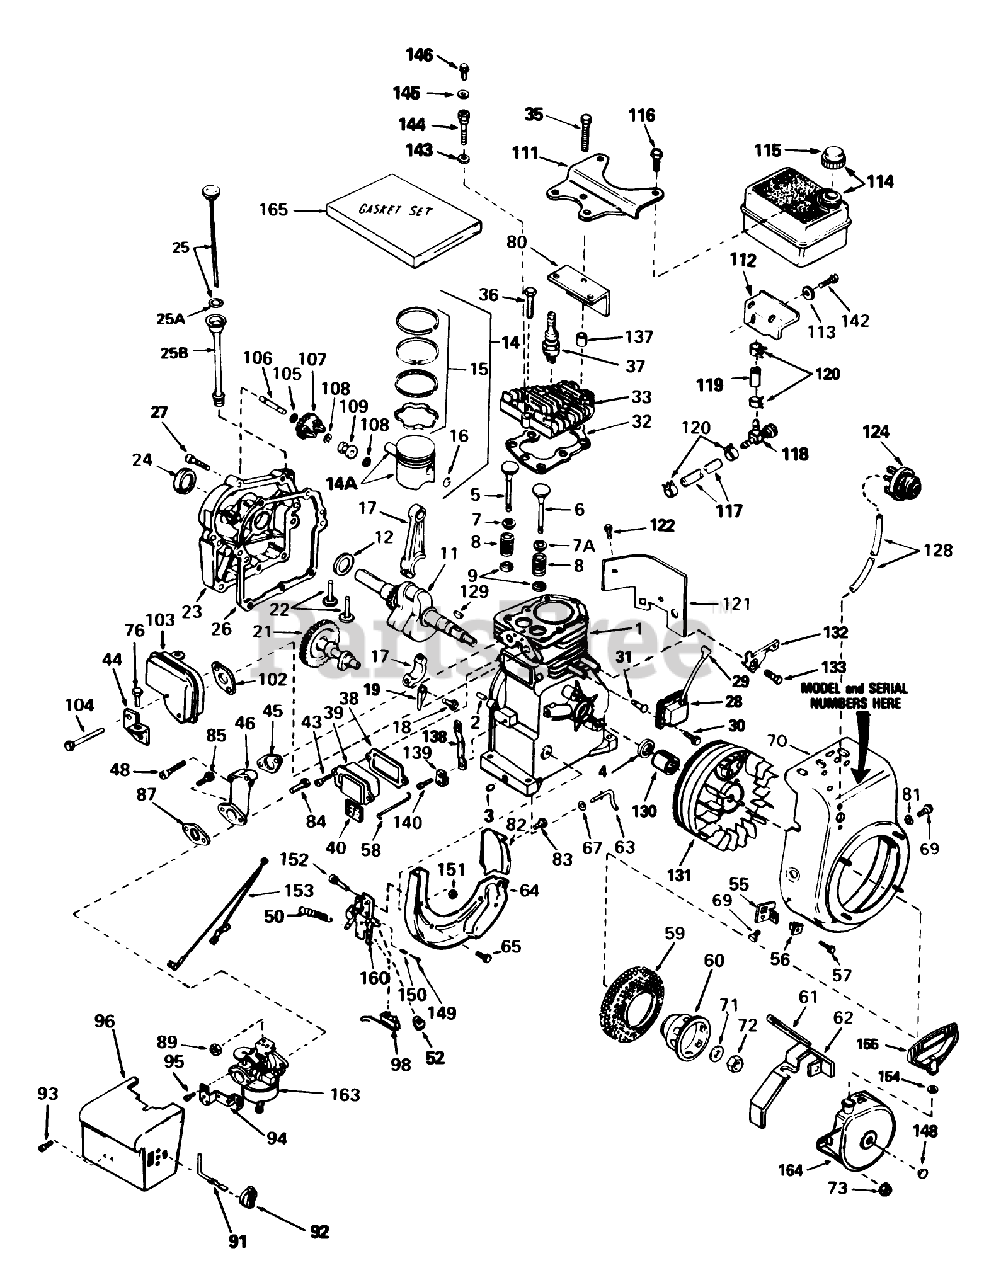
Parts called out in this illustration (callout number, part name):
1	Cylinder Assembly (Incl. Ref. #2, 3 4)
2	Pin-Dowel
3	Plug-Drain, Oil (SQH 1/4-18)
4	Seal-Oil
5	Valve-Intake Standard (Incl. Ref. #151)
5	Valve-Intake 1/32" oversize (Incl. Ref. #151)
6	Valve, Exhaust (Std.)(Incl. No. 40)
6	Valve, Intake (1/32" oversize)(Incl. No. 40)
7	Cap-Upper Valve Spring
7A	Cap, Upper Valve Spg (Exhaust)
8	Spring-Valve
9	Cap-Valve, Spring
11	Crankshaft ASM
12	Washer-Thrust
14	Piston, Pin Ring Assy., (Incl. Ref. #15 16) (Std.)
14	Piston, Pin Ring Assy., (Incl. Ref. #15 16) (.010 Oversize)
14	Piston, Pin Ring Assy., (Incl. Ref. #15 16) (.020 Oversize)
14A	Piston Pin Assy. (Incl. Ref. #16) (Std.)
14A	Piston Pin Assy., (Incl. Ref. #16) (.010 Oversize)
14A	Piston Pin Assy. (Incl. Ref. #16) (.020 Oversize)
15	Ring Set-Piston Std.
15	Ring Set-Piston .010 oversize
15	Ring Set-Piston .020 oversize
16	Ring-Retaining, Piston Pin
17	Rod Assembly, Connecting (Incl. Nos. 17 18)
18	Bolt-Rod, Connecting
19	Dipper-Oil
21	Camshaft
22	Lifter-Valve
23	Cover-Cylinder (Incl. Ref. #59 72)
24	Seal-Oil
25	Dipstick
25A	O-Ring
25B	Tube Fill
26	Gasket-Cylinder Cover
27	Screw (1/4-20 x 1-1/4)
28	Solid State
29	Cover-Spark Plug
30	Screw
32	Oil Fill Tube
33	Head Cylinder
35	Screw (5/16-18 X 2)
36	Screw (5/16-18x1-1/2)
37	Plug, Spark (J17LM or equiv.)
37	Plug, Spark (Champion RCJ-8)
38	Gasket Breather
39	Breather Assembly (Incl. Nos. 52 84)
40	Element-Breather
43	Screw
44	Bracket-Cover, Carburetor
45	Gasket-Intake
46	Pipe-Intake
48	Screw (1/4-20 x 1-19/32)
50	Spring-Extension
52	Knob-Control
55	Bracket
56	Grommet
57	Screw
58	Link-Governor to Throttle
59	Screen-Starter
60	Cup-Starter
61	Seal, Snowguard
62	Guard-Starter
63	Rod-Governor
64	Baffle-Blower Housing
65	Screw (1/4-20x19/32)
67	Washer-Flat
69	Screw
70	Housing-Blower
71	Washer-Belleville
72	Nut-Flywheel
73	Nut and Lock Washer (1/4-28)
76	Screw (10-24 x 3/8)
80	Baffle-Heat
81	Washer
82	Baffle-Extension
83	Screw-Hex Washer Hd.
85	Screw (1/4-28 x 1-11/16)
87	Gasket
89	Nut and Lock Washer (1/4-28)
91	Rod-Choke
92	Knob-Control
93	Screw (8-32 X 5/16)
94	Bracket-Choke
95	Screw (10-32 x 1/2)
96	Cover-Carburetor
98	Terminal
102	Gasket-Exhaust
103	Muffler
104	Screw-Fil. Hd.
105	Washer-Flat
106	Shaft-Governor
107	Governor Gear ASM
108	Ring-Retaining
109	Spool-Governor
111	Bracket, Fuel Tank-Upper
112	Bracket-Fuel Tank
113	Washer
114	481-1261 SENATOR TI
115	Cap, Fuel
116	Screw (1/4-15x7/8)
117	Line-Fuel
118	Valve-Shut Off
119	Line-Fuel (8.62)
120	Clamp-Line, Fuel
121	Extension-Blower
122	Screw
124	Primer Assy.
128	Line-Primer
129	Key-Flywheel
130	Spacer
131	CLAMP
132	Bracket-Hold Down
133	Screw (10-24 x 9/16)
137	pacer
138	Lever-Governor
139	Clamp-Lever, Governor
140	Screw
142	Screw Assembly
143	Washer-Flat
144	Screw ( 5/16-18 x 1-1/2)
145	Washer
146	Screw
148	Plug-Starter
149	Screw
150	Spring-Compression
151	Nut-Lock
152	Screw
153	Ground Wire
154	Washer
155	Handle-Starter, Mitten Grip
160	Control Assembly, Speed (Incl. Ref. #155 thru 158 160)
163	Carburetor (Incl. Ref. #87)
164	Starter-Rewind
165	Gasket Set
